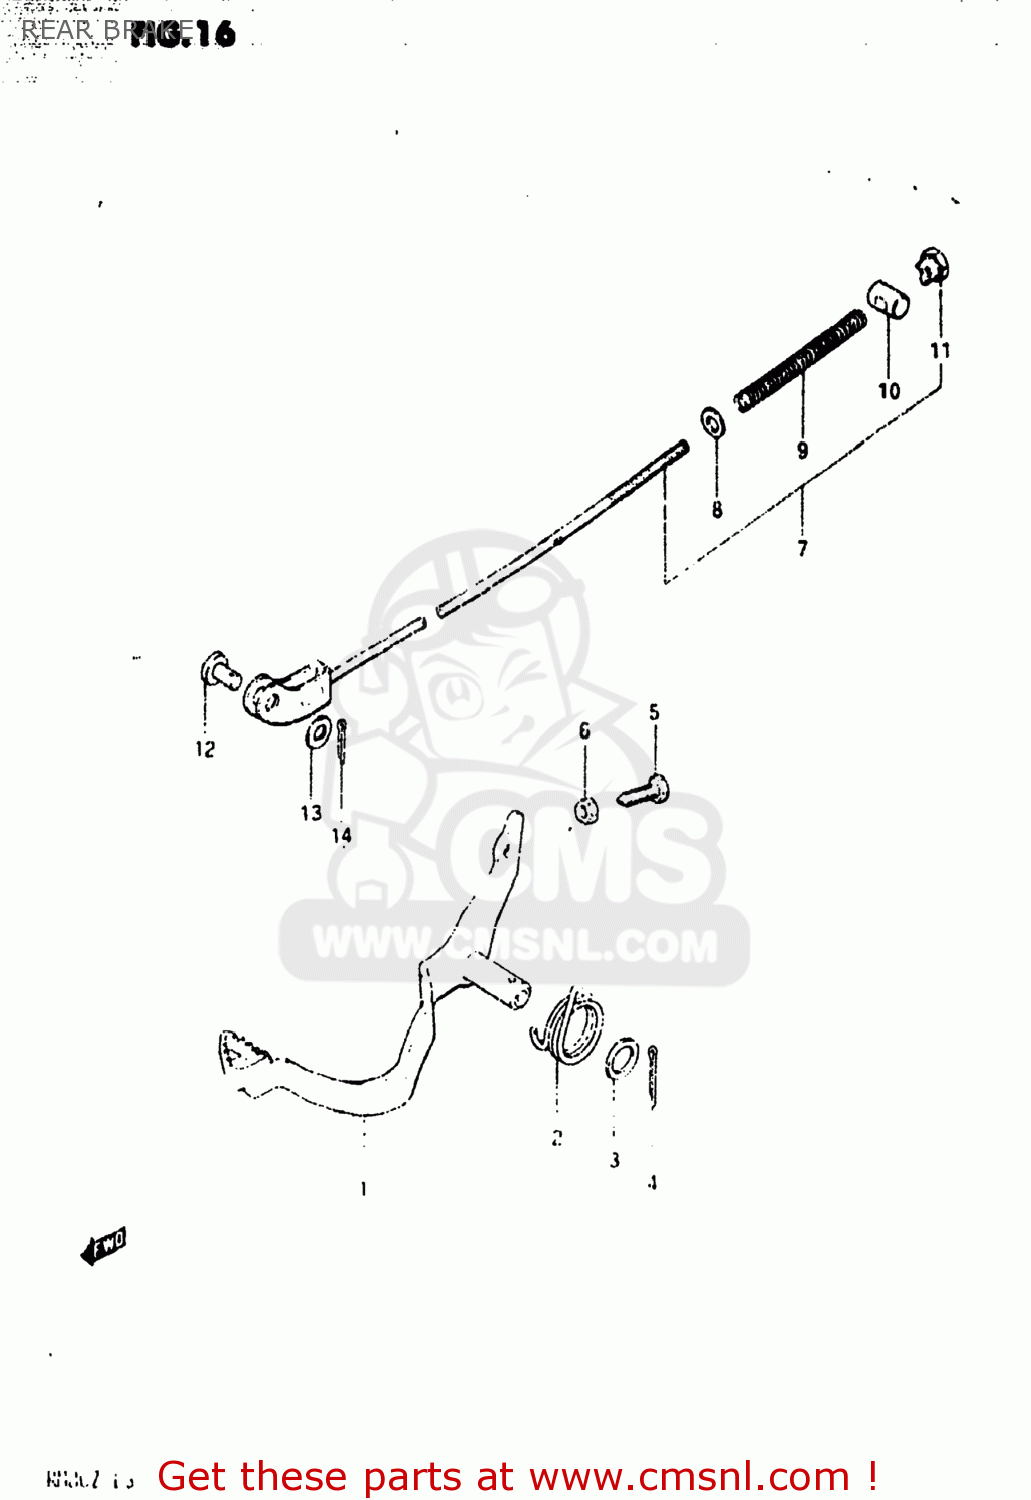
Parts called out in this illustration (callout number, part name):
1	PEDAL,BRAKE
2	SPRING
3	WASHER(15.5X26X2.3)
4	COTTER PIN
5	SCREW(6X23)
6	NUT
7	ROD ASSEMBLY,REAR BRAKE
8	WASHER
9	SPRING
10	PIN(11X18)
11	NUT
12	PIN
13	WASHER
14	PIN 20X20
